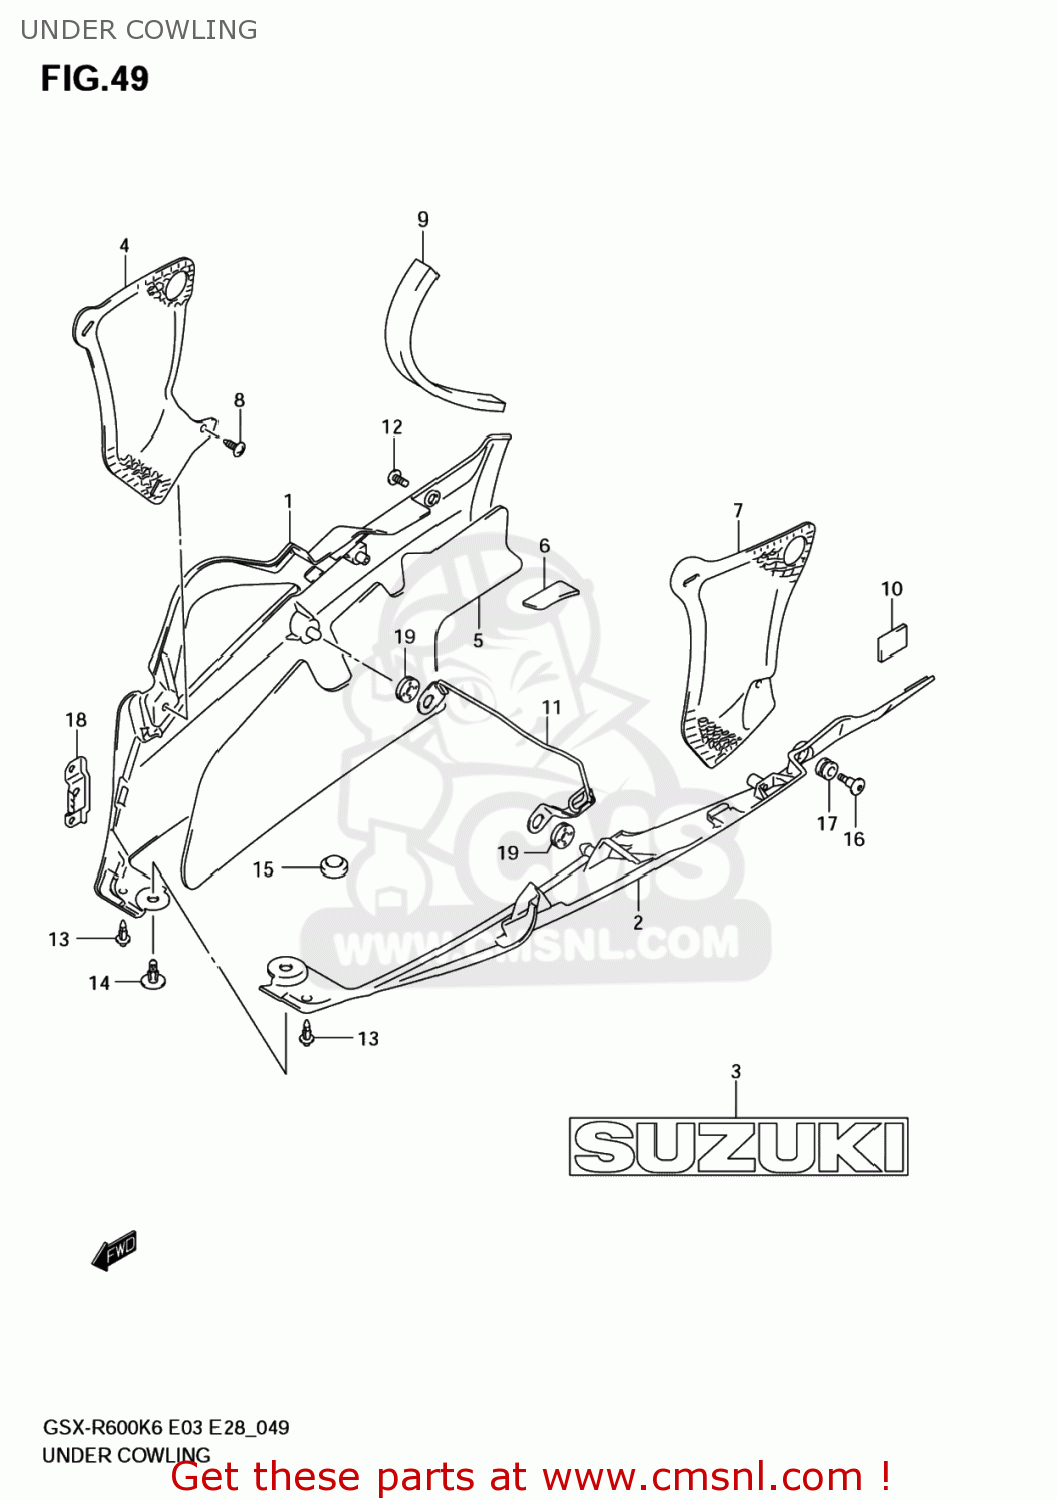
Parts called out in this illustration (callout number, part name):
1	COWLING,UNDER,
2	COWLING,UNDER,L(BLACK)
3	EMBLEM,SUZUKI
4	SHIELD,UNDER COWL HEAT,R
5	SHIELD,UNDER COWL HEAT,R
6	SHIELD,UNDER COWL HEAT
7	SHIELD,UNDER COWL HEAT,L
8	SCREW
9	CUSHION,COWLING
10	CUSHION
11	BRACKET,UNDER COWLING LWR
12	SCREW(5X13)
13	CLIP(BLACK)
14	CLIP
15	CUSHION
16	SCREW(6X20)
17	CUSHION
18	PLATE,UNDER COWL
19	CUSHION
